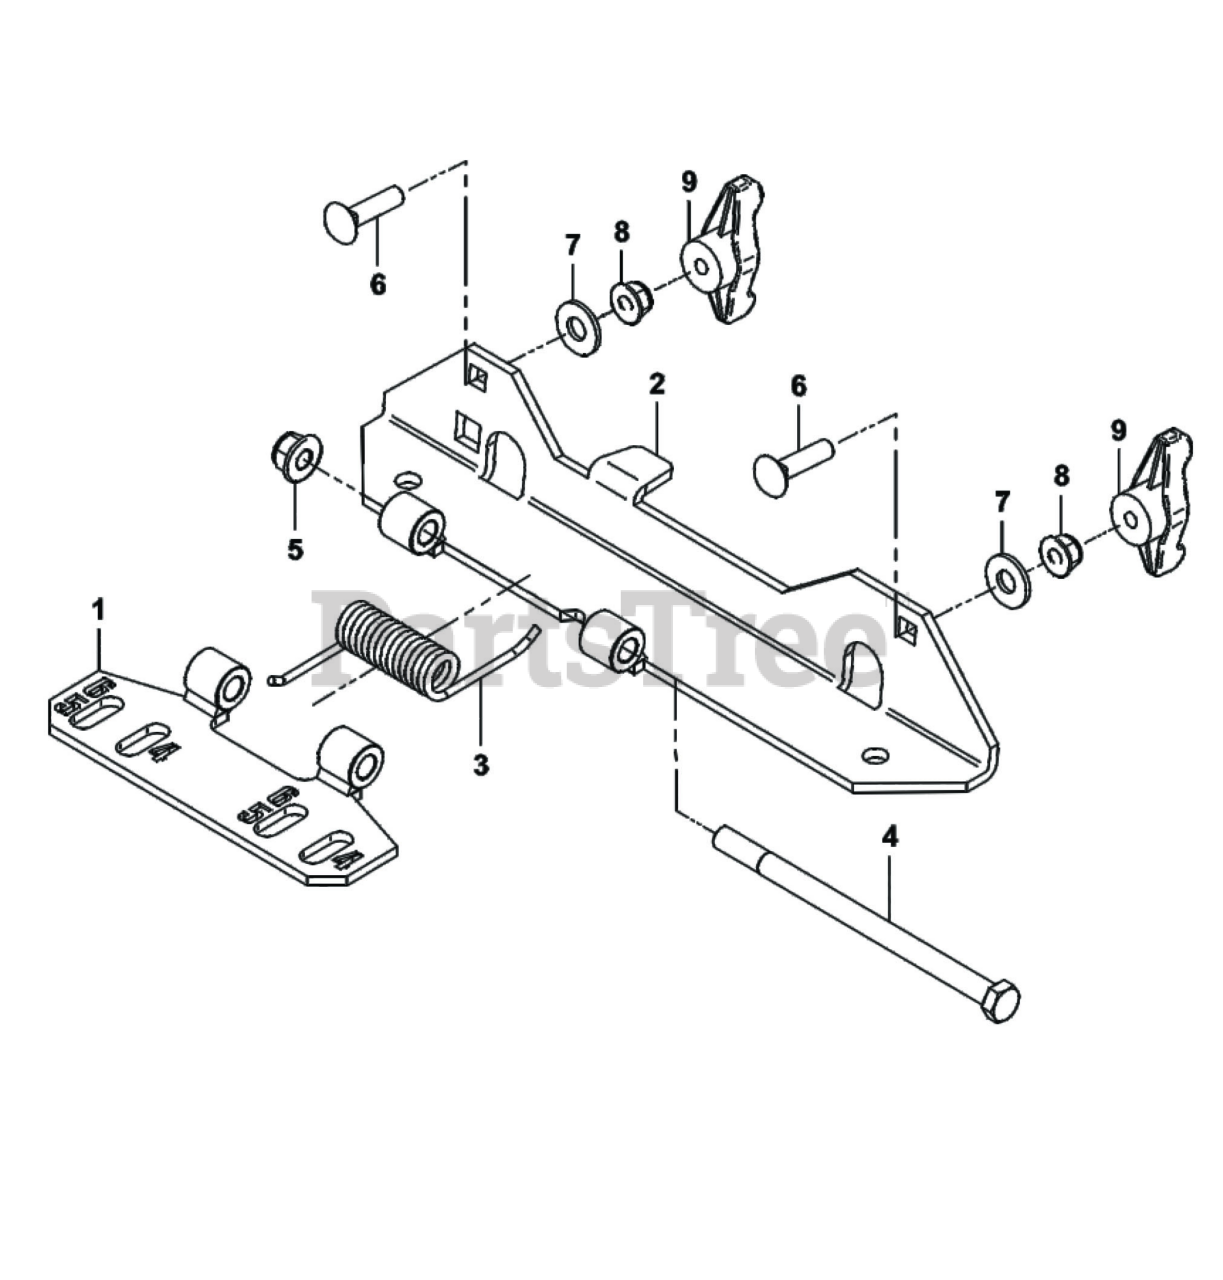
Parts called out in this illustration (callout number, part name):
1	BOOT PLATE ASSEMBLY
2	DECK PLATE ASSEMBLY
3	TORSION SPRING
4	SCREW 3/8"-16 x 6" (GR5)
5	LOCKNUT-NYLON FLAN
6	CARRIAGE BOLT 5/16"-18 X 1.25"
7	FLAT WASHER
8	NUT-FLANGE LOCK 5/
9	WING KNOB (5/16"-18)
